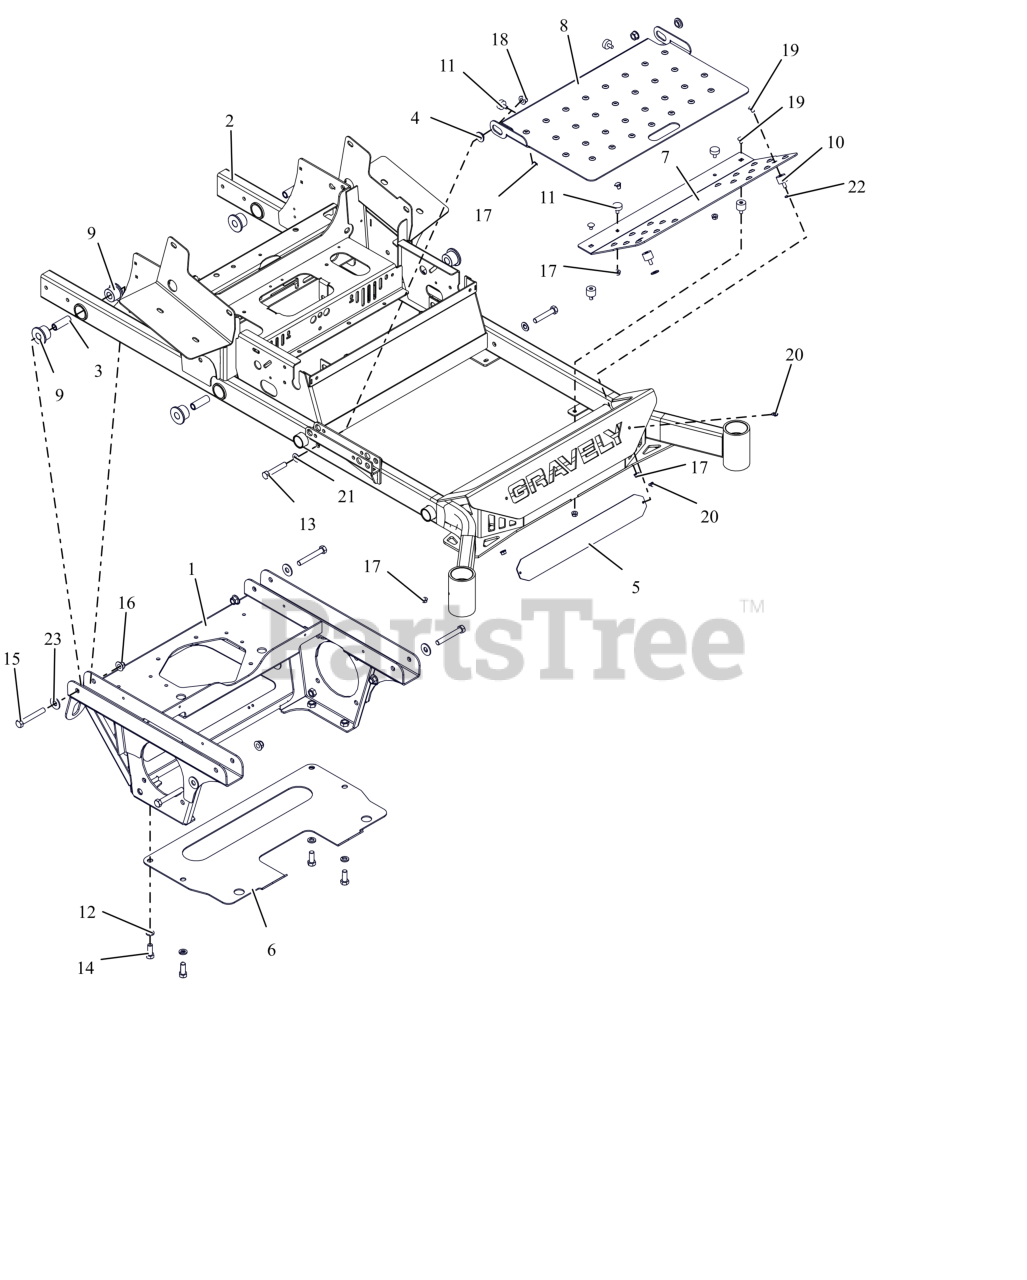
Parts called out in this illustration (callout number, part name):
1	PT200/400 AXLE/ENG FRM WMT-RED
2	52-60"PT200/400 FRAME W/DECALS
3	BSHG-SLV .50X.75X2.23
4	BSHG-FLG .515X.750X.310X1.120
5	BUMPER LOGO BACKING PLATE -BLK
6	PLATE-TRANSMISSION SKID
7	FOOTREST W/ SAFTEY DECALS
8	INSPECTION PANEL W/SAFE DECAL
9	BSHG-FLG .75X1.51X1.13X2.0 URE
10	BUMPER,STUD MNTD W/FEMALE INSR
11	BUMPER, RUBBER
12	WSHR,LK-REG .500X.125 ZCC
13	BLT,HEX .50-13X2.75 G5 ZCC
14	BLT,HEX .50-13X1.25 G5 ZCC
15	BLT, HEX .50-13X3.50 G5 ZCC
16	NUT,NYL-FLG .50-13 GF ZCC
17	NUT,SPNLK-FLG .31-18 G5 ZCC
18	NUT-LK-CTR-FLG .500-13 GG ZCC
19	BTL,RHSN .313-18 X 0.5 G5 ZCC
20	SCR-TAP .25-20X.50 HWH ZCC
21	WSHR, FLT .531X1.00X.063 ZCC
22	WSHR,FLT .375X.875X.083 ZCC
23	WSHR,FLT .563X1.375X.109 ZCC
